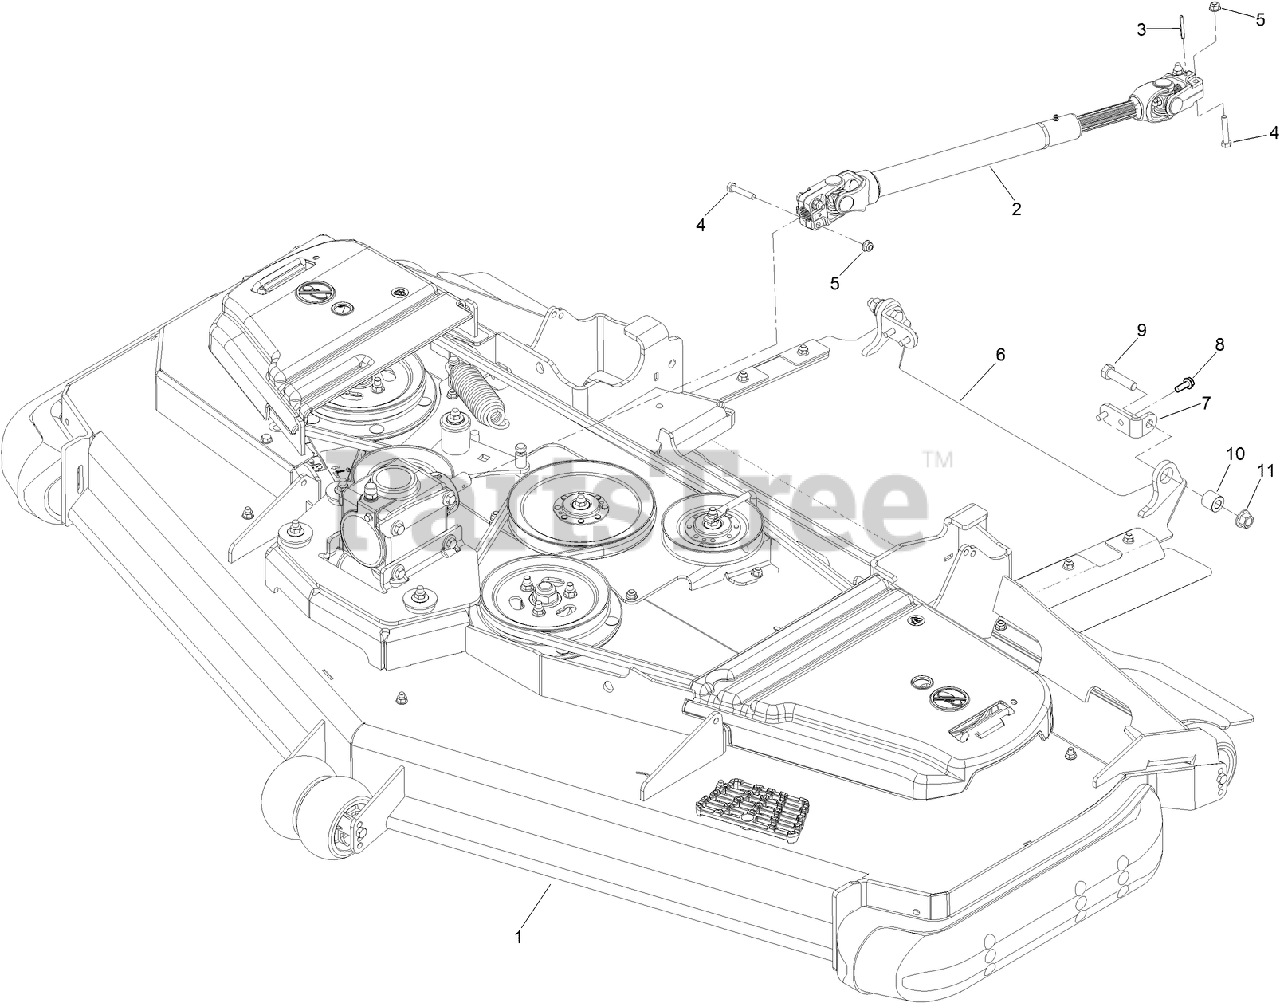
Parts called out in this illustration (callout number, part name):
1	DECK ASM
2	DRIVESHAFT ASM
3	PIN-ROLL
4	SCREW-HH
5	NUT-HF, NI
6	DISCHARGE TUNNEL ASM
7	BRACKET-DISCHARGE
8	SCREW-TAPTITE
9	SCREW-HH
10	BUSHING-SLEEVE
11	NUT-LOCK
